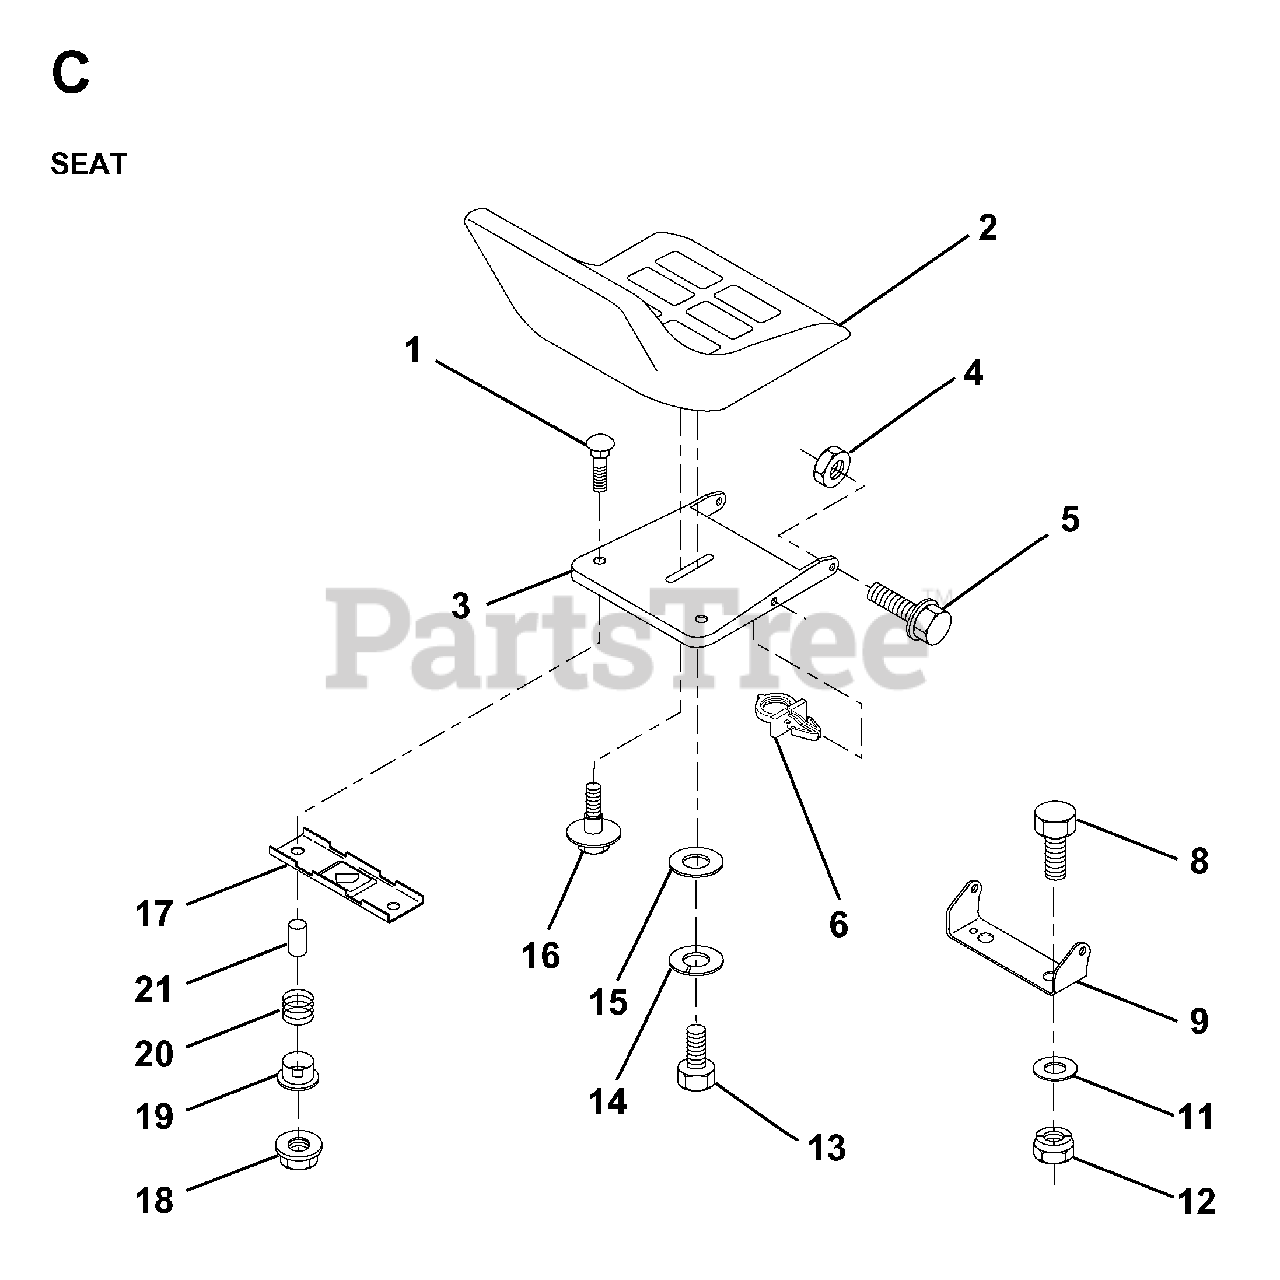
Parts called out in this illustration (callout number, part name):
1	BOLT.ROUND.HEAD.SQUARE.NECK
2	SEAT
3	PAN, SEAT
4	NUT.71038.31-18.HEX.NYLOCK
5	BOLT SHOULDER 5/16-18
6	PUSH CLIP
8	BOLT
9	SEAT PIVOT BRKT
11	WASHER 12/32X2X10GA
12	NUT
13	BOLT
14	LOCKWASHER
16	BOLT,SHOULD
17	BRKT SWITCH
18	NUT T
21	SPACER SPLIT 28X.96
